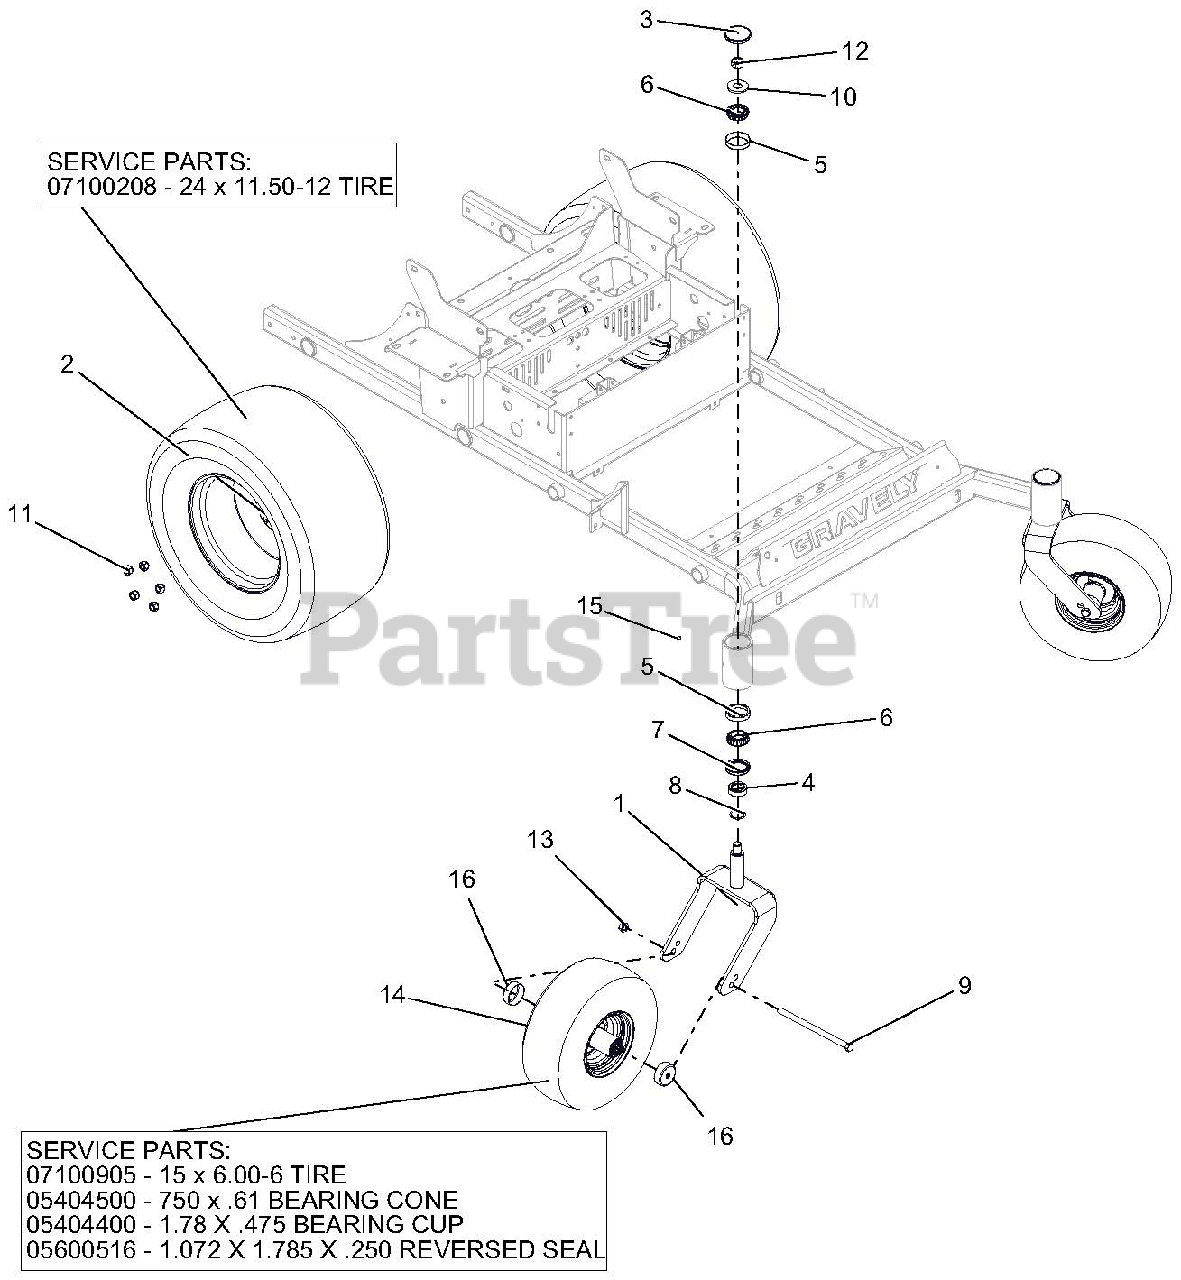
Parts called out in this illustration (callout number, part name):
1	WMT, CASTER FORK
2	TIRE/WHEEL, ASM 24X11.50-12
2	24 X 11.50-12 TIRE
3	CAP, DUST
4	SPCR, FRONT CASTER FORK
5	BRG, CUP 2.328 X .465
6	BRG, CONE 1.250 X .660
7	SEAL, OIL 1.75 X 2.332 X .312
8	O-RING, .139 W X 1.234 ID
9	BLT-HEX .50-13X9.00 GR5 YWZC
10	WSHR-FL-STL.812X2.00X.148YWZC
11	NUT, LUG .500-13
12	@NUT-LK-CTR-JAM .75-16 YWZC
13	NUT, LK-TOP-FLG .50-13 YWZC
14	TIRE/WHEEL, 15 X 6.00-6 SMOOTH
14	15 x 6.00-6 TIRE
14	750 x .61 BEARING CONE
14	1.78 X .475 BEARING CUP
14	1.072 X 1.785 X .250 REVERSED SEAL
15	FITTING, .250-28 FLUSH MOUNT GREASE
16	SHIELD, WHEEL BEARING
